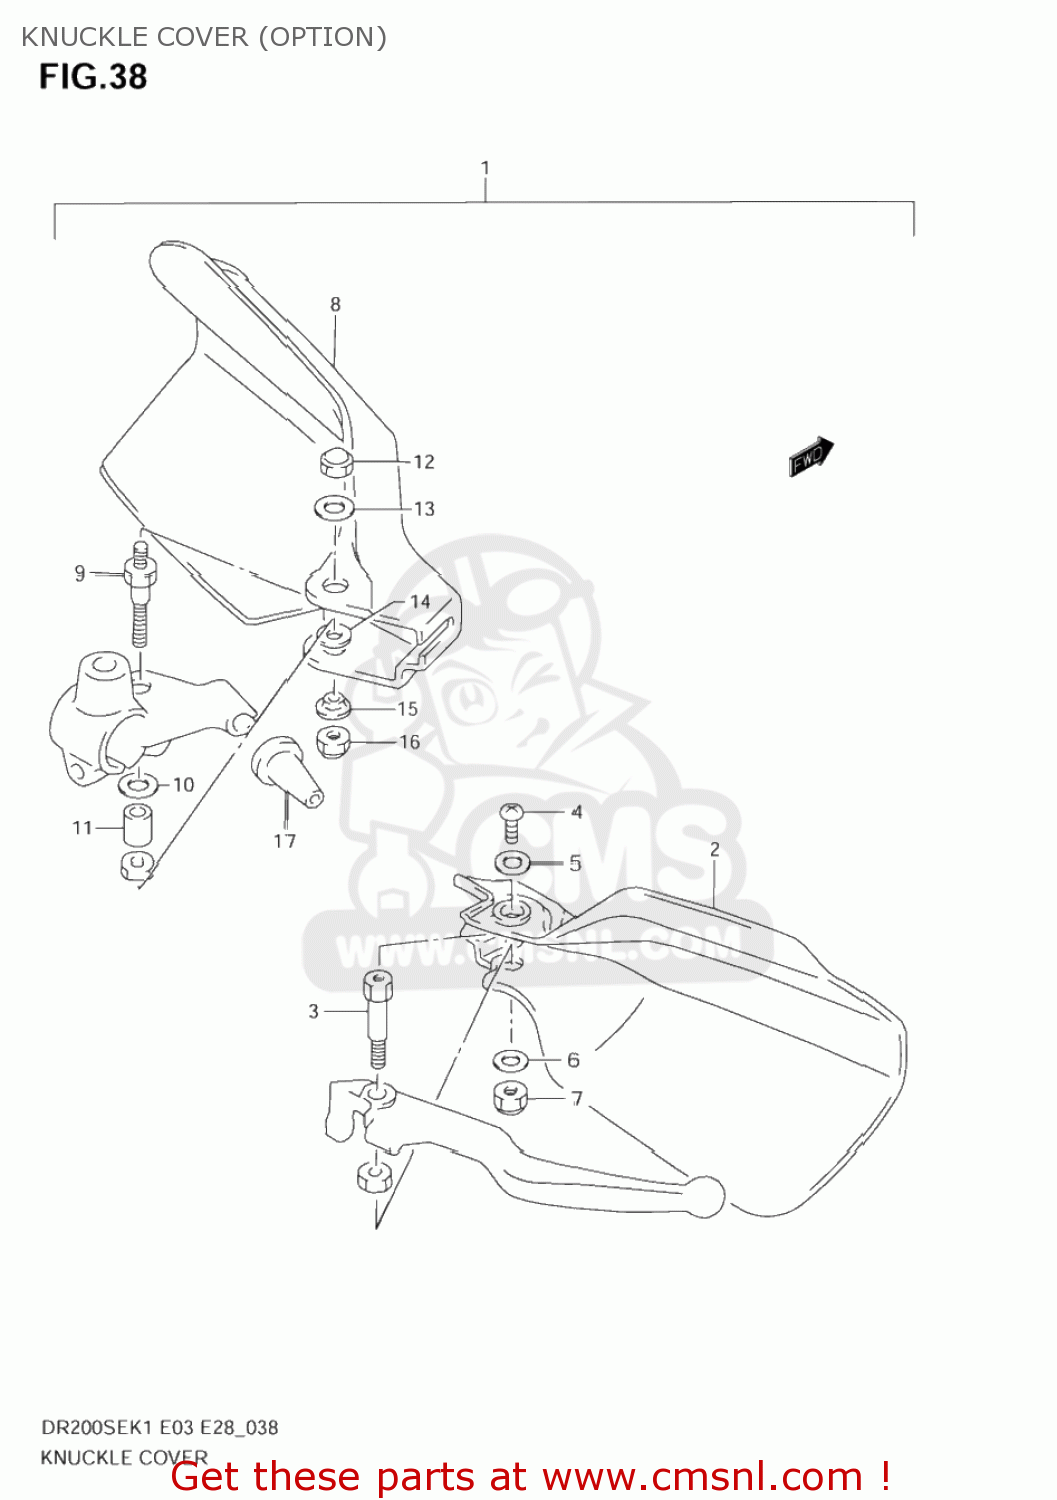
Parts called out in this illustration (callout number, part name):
1	COVER SET,KNUCKLE
2	COVER,KNUCKLE,R
3	BOLT,BRAKE LEVER PIVOT
4	SCREW
5	WASHER(5.5X16X1.2)
6	WASHER(6.5X16X1.6)
7	NUT 6MM
8	COVER,KNUCKLE,LEFT
9	BOLT,CLUTCH LEVER PIVOT
10	WASHER,LEVER SET
11	SPACER,LEVER SET
12	NUT
13	WASHER(6.5X20X1.6)
14	WASHER(6.5X16X1.2)
15	WASHER
16	NUT 6MM
17	BOOT,CLUTCH CABLE
